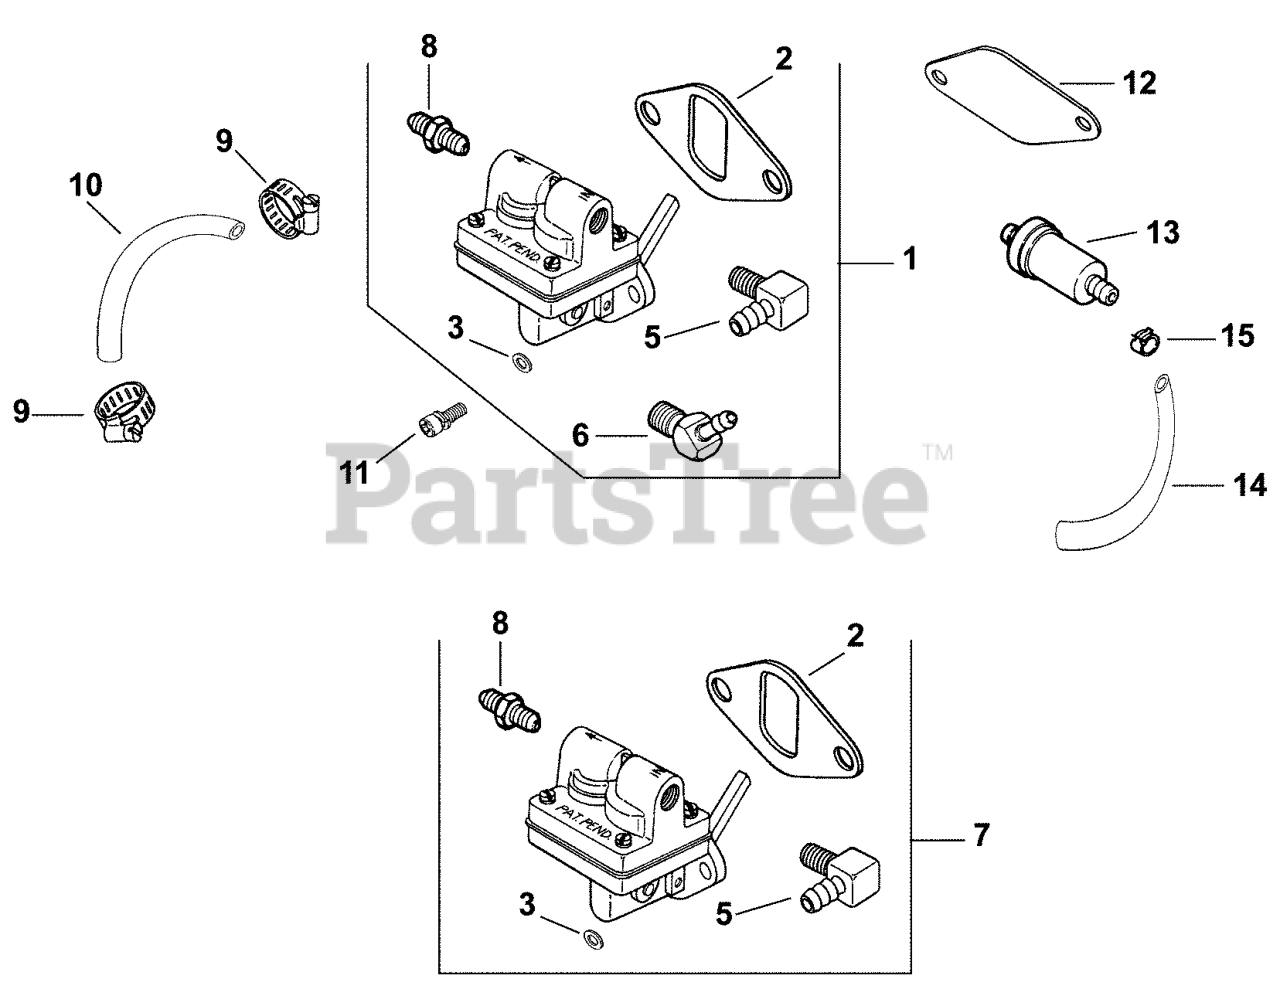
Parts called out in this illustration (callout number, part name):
1	FUEL PUMP WITH GASKET - USE 47 559 04-S
2	GASKET, FUEL PUMP - USE 25 041 09-S
3	WASHER - USE X-25-63-S
4	CONNECTOR - USE X-391-11-S
5	CONNECTOR - USE 25 155 02-S
6	FITTING - USE 47 155 12-S
